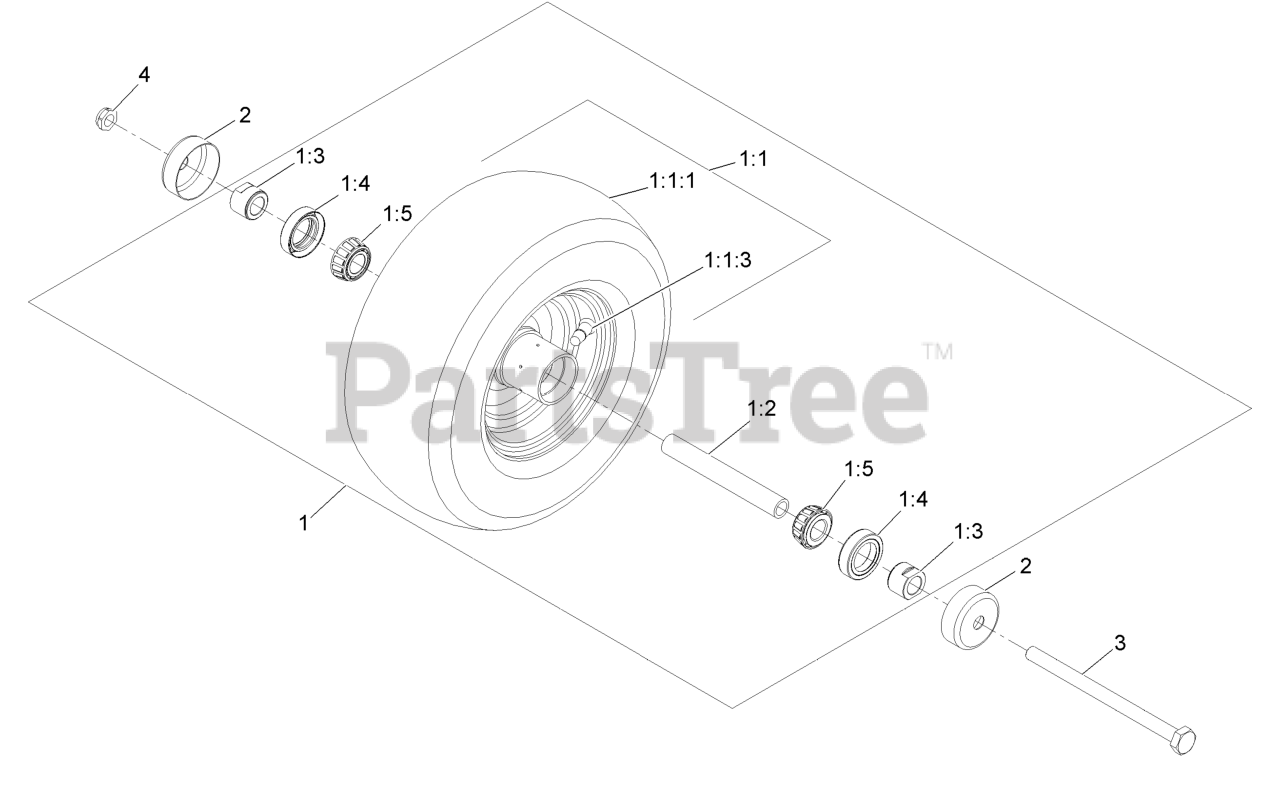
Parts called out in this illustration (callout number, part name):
1:1:3	VALVE
1:3	SPACER-NUT
1:4	SEAL-CASTER
1:5	BEARING-CONE, TAPERED ROLLER
2	GUARD-SEAL
3	SCREW-HH
4	NUT-HEX
